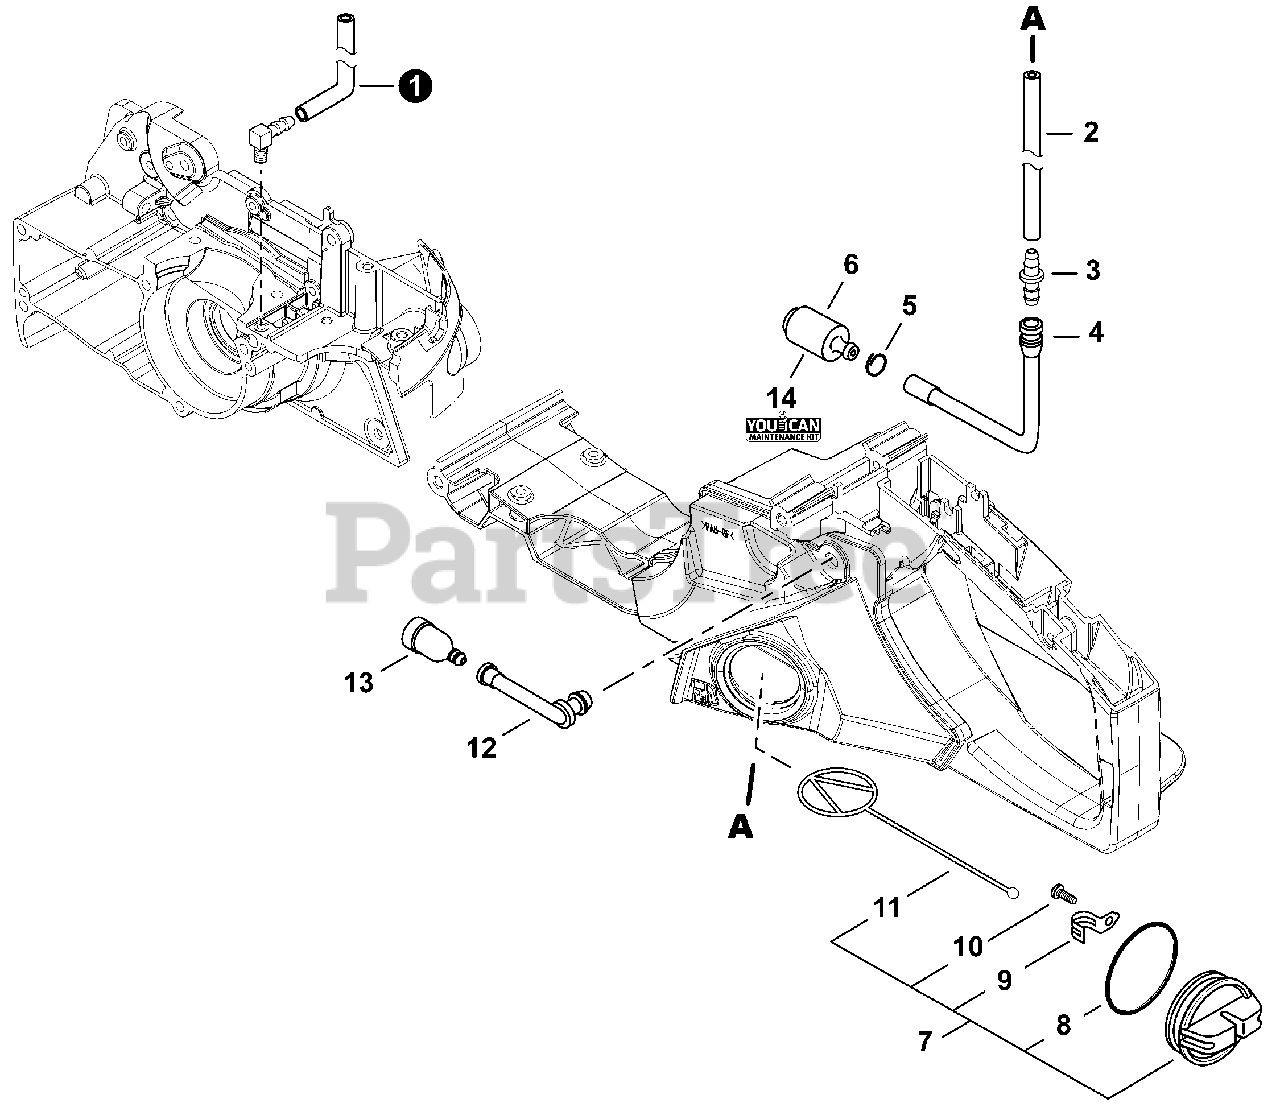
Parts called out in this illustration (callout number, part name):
1	PIPE, PULSE
2	PIPE, FUEL 3×6×75
3	CONNECTOR, PIPE
4	PIPE, FUEL
5	CLIP Ø6
6	FILTER, FUEL
7	CAP ASSY, FUEL
8	O-RING 29
9	CONNECTOR, CAP L= 60 MM
10	PIPE, FUEL VENT
11	VENT ASSY
12	TUNE-UP KIT - YOUCAN™
